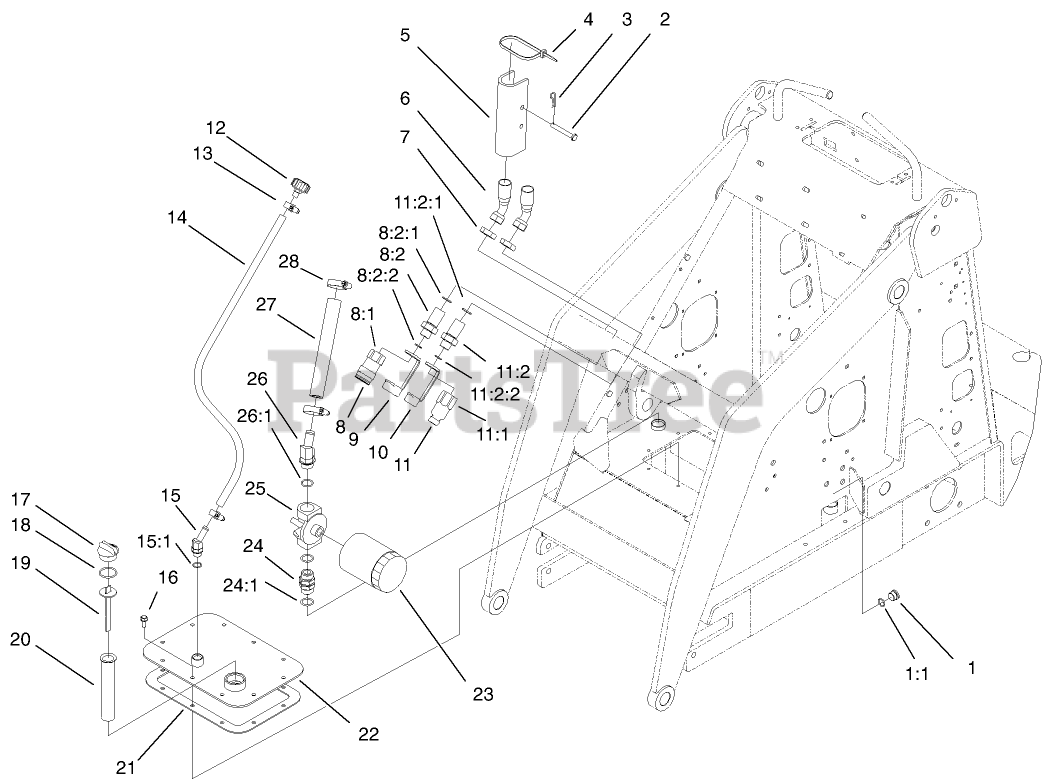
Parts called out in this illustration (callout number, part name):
1	PLUG-HEX
1:1	O-RING
2	PIN-CLEVIS
3	PIN-HAIR
4	TIE-CABLE
5	LOCK-CYLINDER
6	HOSE-HYD
7	NUT-LOCK, BULKHEAD
8	BULKHEAD COUPLER ASM
8:1	COUPLER-FACE, FLUSH
8:2	FITTING-ADAPTER, BULKHEAD
8:2:1	O-RING
8:2:2	O-RING
9	CAP-DUST, COUPLER
10	CAP-DUST, NIPPLE
11	BULKHEAD NIPPLE ASM
11:1	NIPPLE-FACE, FLUSH
11:2	FITTING-ADAPTER, BULKHEAD
11:2:1	O-RING
11:2:2	O-RING
12	BREATHER
13	CLAMP-HOSE
14	HOSE-VENT
15	FITTING-HYD, 45 DEG
15:1	O-RING
16	SCREW
17	PLUG-PLASTIC
18	O-RING
19	DIPSTICK-OIL
20	FILTER-SCREEN
21	GASKET-COVER
22	COVER
23	FILTER-OIL, TRANSMISSION
24	FITTING-THREAD, STRAIGHT
24:1	O-RING
25	HEAD-FILTER
26	ELBOW-45 DEG
26:1	O-RING
27	HOSE-HYD
28	CLAMP-HOSE
